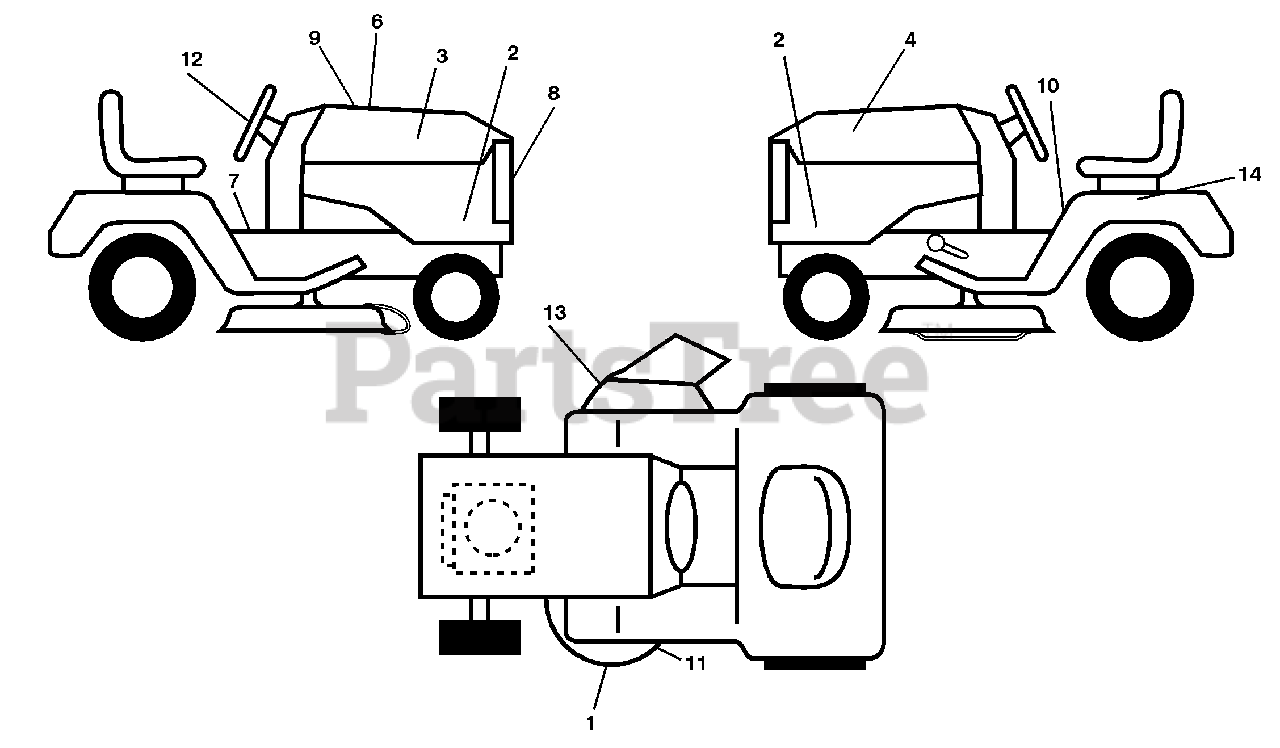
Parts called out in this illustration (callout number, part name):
1	Decal Deck Hvy Duty
2	Decal Panel Side
3	Decal Hood RH
4	Decal Hood LH
6	Decal Hood Cust. Resp.
7	Decal Operator
8	Decal Dash
9	Decal Replacement
10	Decal Fender Danger
11	Decal V-Belt Sch.
12	Decal Wheel Steering
13	Decal Warning
14	Decal Bat Dan/Psn
